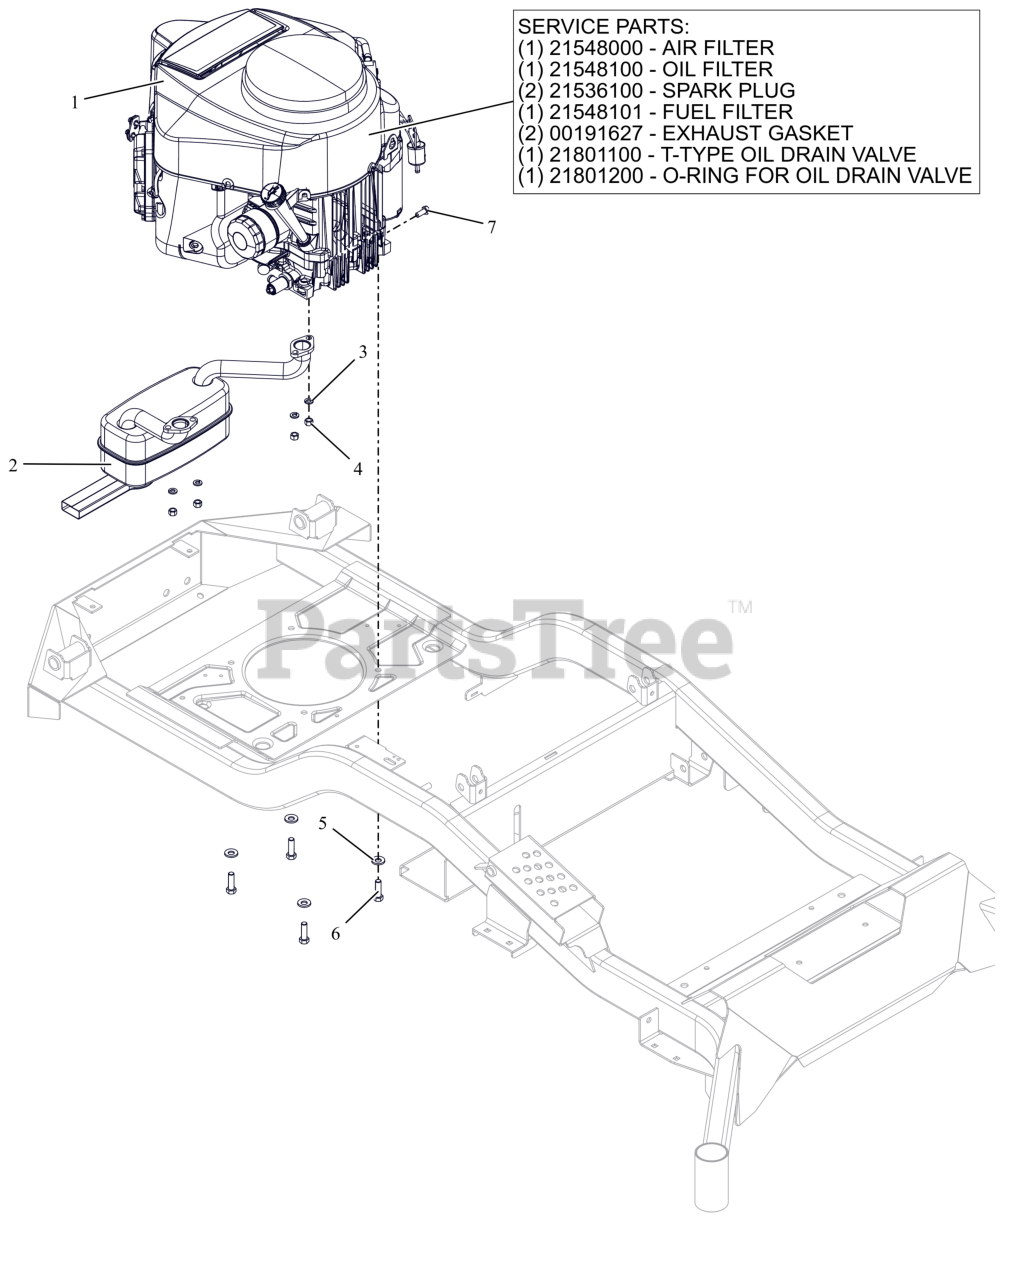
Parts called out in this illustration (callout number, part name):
1	ENGINE, KAWASAKI FR730 24HP
1	AIR FILTER, KAWASAKI FR
1	OIL FILTER, KAWASAKI FR
1	PLUG, SPARK
1	FUEL FILTER-KAWASAKI FR
1	GASKET, MUFFLER S/O
1	T-TYPE OIL DRAIN VALVE
1	O-RING FOR OIL DRAIN VALVE
2	MUFFLER, KAWASAKI
3	WSHR,LK-REG .312X.078 ZCC
4	NUT-LK-TOP-FLG M8 ZCC
5	WASHER, 3/8" SPRING DISC
6	BLT, HEX .38-16X1.25 G5 ZCC NT
7	BLT, HEX M8-1.25X20 G8.8 ZCC
